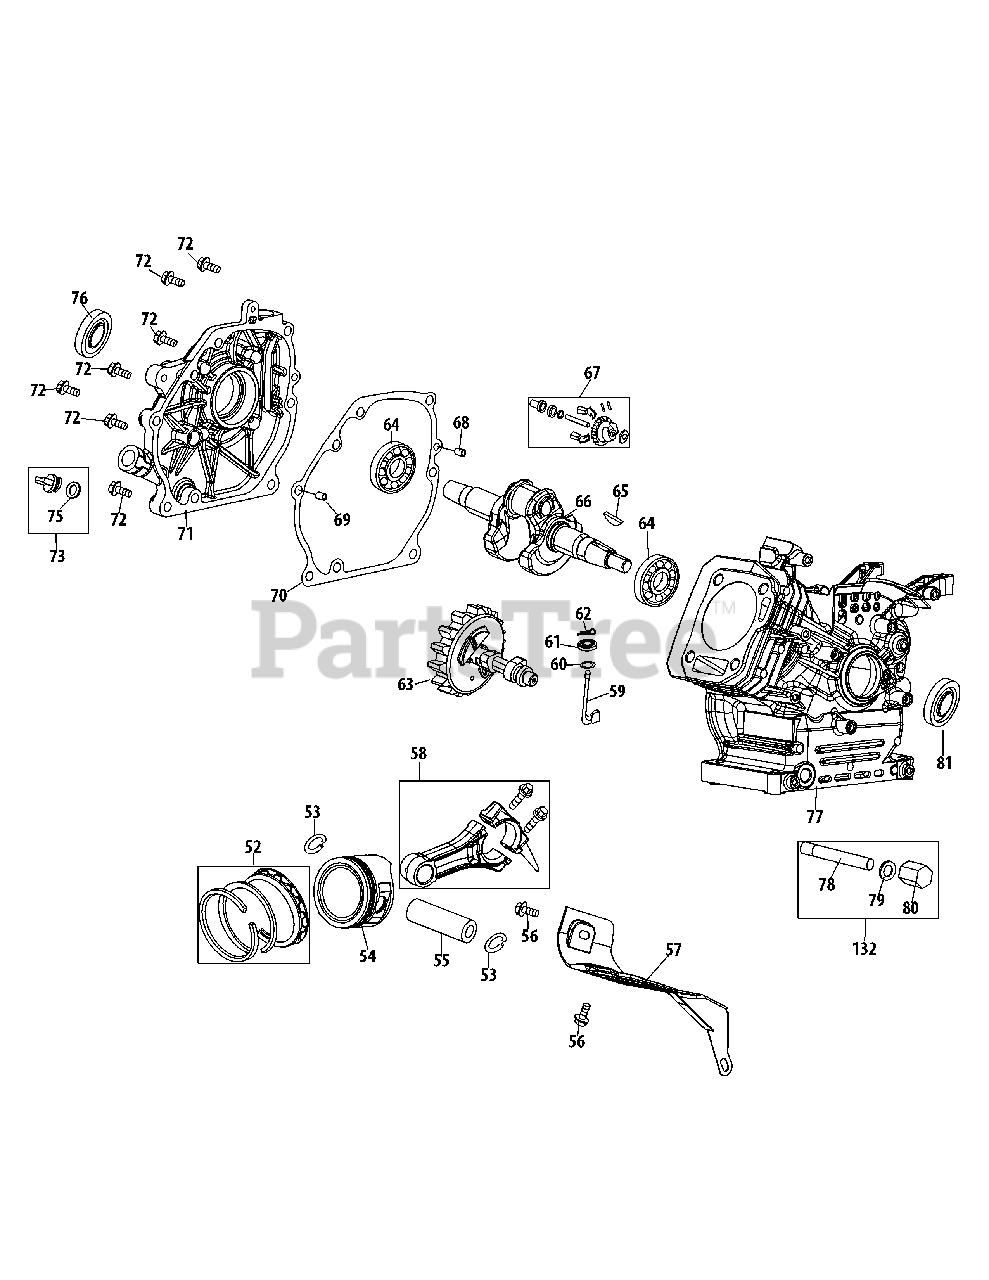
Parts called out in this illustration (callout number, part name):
52	Piston Ring Set
53	Piston Pin Snap Ring
54	Piston
55	Piston Pin
56	Bolt M6×12
57	Air Shield
58	Connecting Rod Assembly
59	Governor Arm Shaft
60	Washer 5.2×1.9
61	Governor Seal
62	Cotter Pin
63	Camshaft Assy.
64	Radial Ball Bearing
65	Woodruff Key
66	Crankshaft Kit
67	Governor Gear/Shaft Assembly
68	Dowel Pin 7×14
69	Dowel Pin 9×14
70	Crankcase Cover Gasket
71	Cover Comp, Left Crankcase
72	Bolt M8×32
73	Oil Fill Plug Assembly
75	O-Ring 15.8×2.5
76	Oil Seal 25×41.25×6
77	Crankcase Kit
78	Oil Drain Pipe Assy.
79	Washer 10x16×1.5
80	Oil Drain Plug
81	Oil Seal 25×41.25×6
132	Oil Drain Assembly
